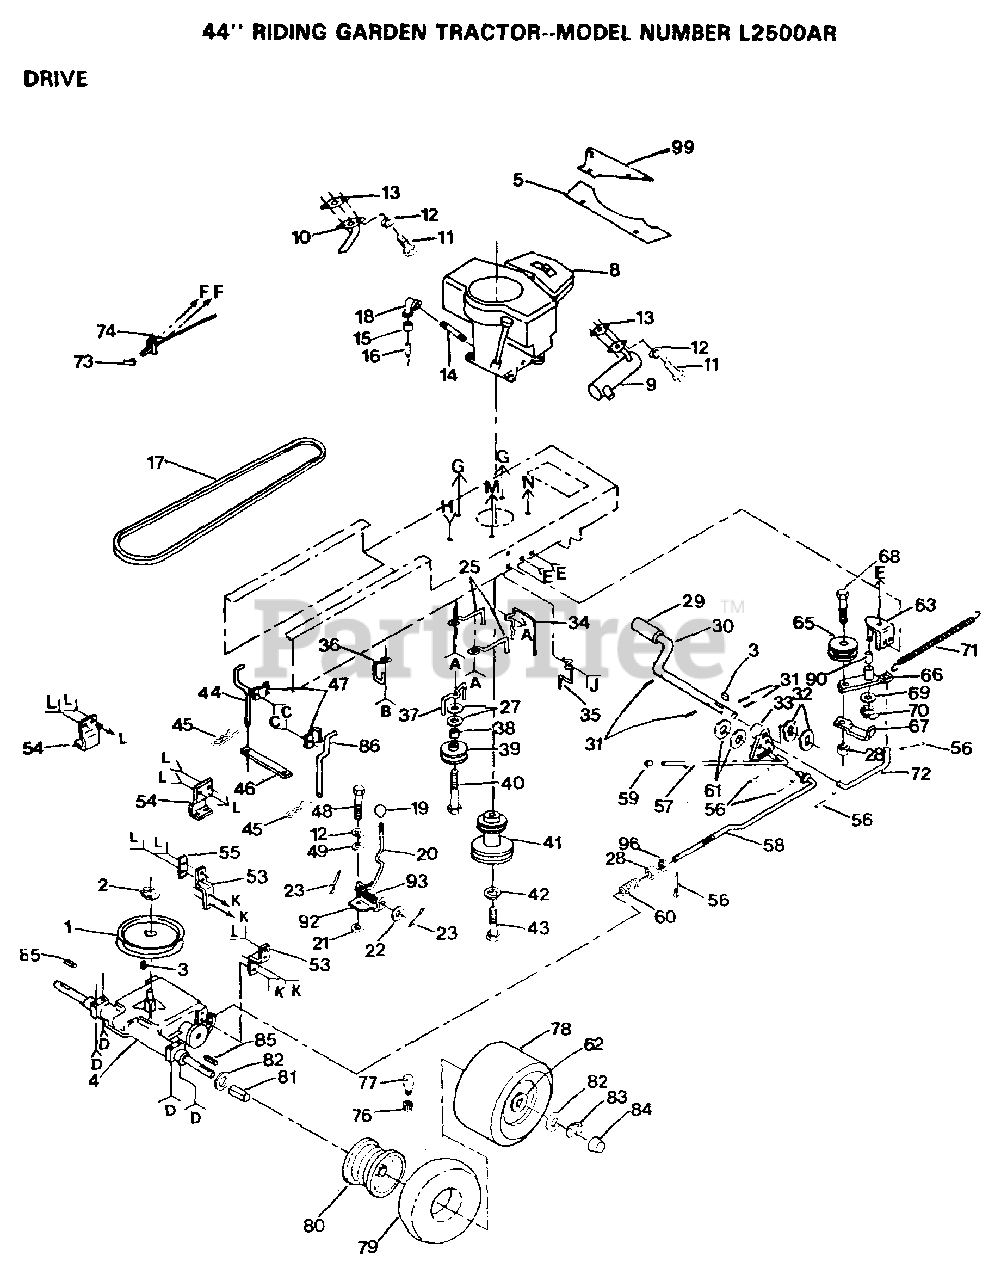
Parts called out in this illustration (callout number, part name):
1	Pulley, Transaxle
10	EXHAUST TUBE T
12	LOCKWASHER
14	PIPE NIPPLE
16	PLUG T
18	STREET ELBOW LT
19	KNOB T (1/2-HOLE)
21	WASHER
22	WASHER
23	PIN COTTER 1/8
25	"KEEPER,BLT ENG LT"
27	WASHER
29	PEDAL COVER T
30	FOOT SHAFT PEDAL
33	ARM BRAKE LT
37	BELT KEEPER LT
38	SPACER T
40	BOLT
42	LOCKWASHER
45	SPRING.RETAINER
47	CLAMP LT
49	WASHER LT
53	STRAP TORQUE LT
54	BRACKET LT
55	PLATE-STRAP LT
56	COTTER PIN
59	PLUNGER CAP T
60	SPRING ROD LT
61	WASHER
69	WASHER T
70	KLIP RING
71	"SPRING, RETURN LT"
72	"LINK, CLUTCH T"
74	THROTTLE CNTRL LT
76	VALVE CAP
77	VALVE STEM LT
79	TUBE.18X9.5-8
80	"RIM ASSY 10"" T"
81	"SPACER, SPLIT LT"
83	E-RING LT
86	KEEPER BELT RH
90	"LY, BEARING"
92	PLATE T
93	SPRING LT
96	NUT
